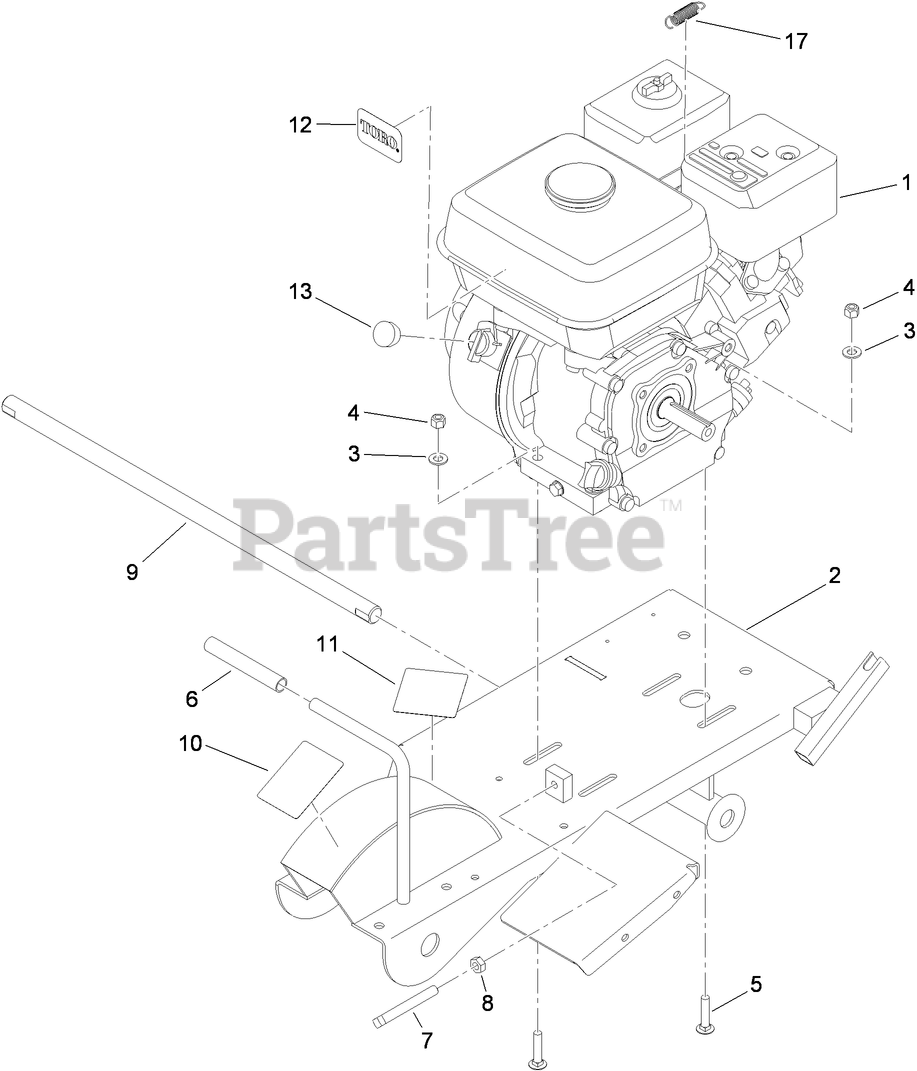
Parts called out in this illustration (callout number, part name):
2	FRAME ASM
3	WASHER-FLAT
4	NUT-LOCK, NI
5	BOLT-CARR
6	GRIP-RUBBER
7	SCREW-SET, SQH
8	NUT-HEX
9	BAR-AXLE, WHEEL
10	DECAL-DANGER
11	DECAL-CAUTION
12	Decal
13	PLUG-ENGINE
17	SPRING-EXTENSION
